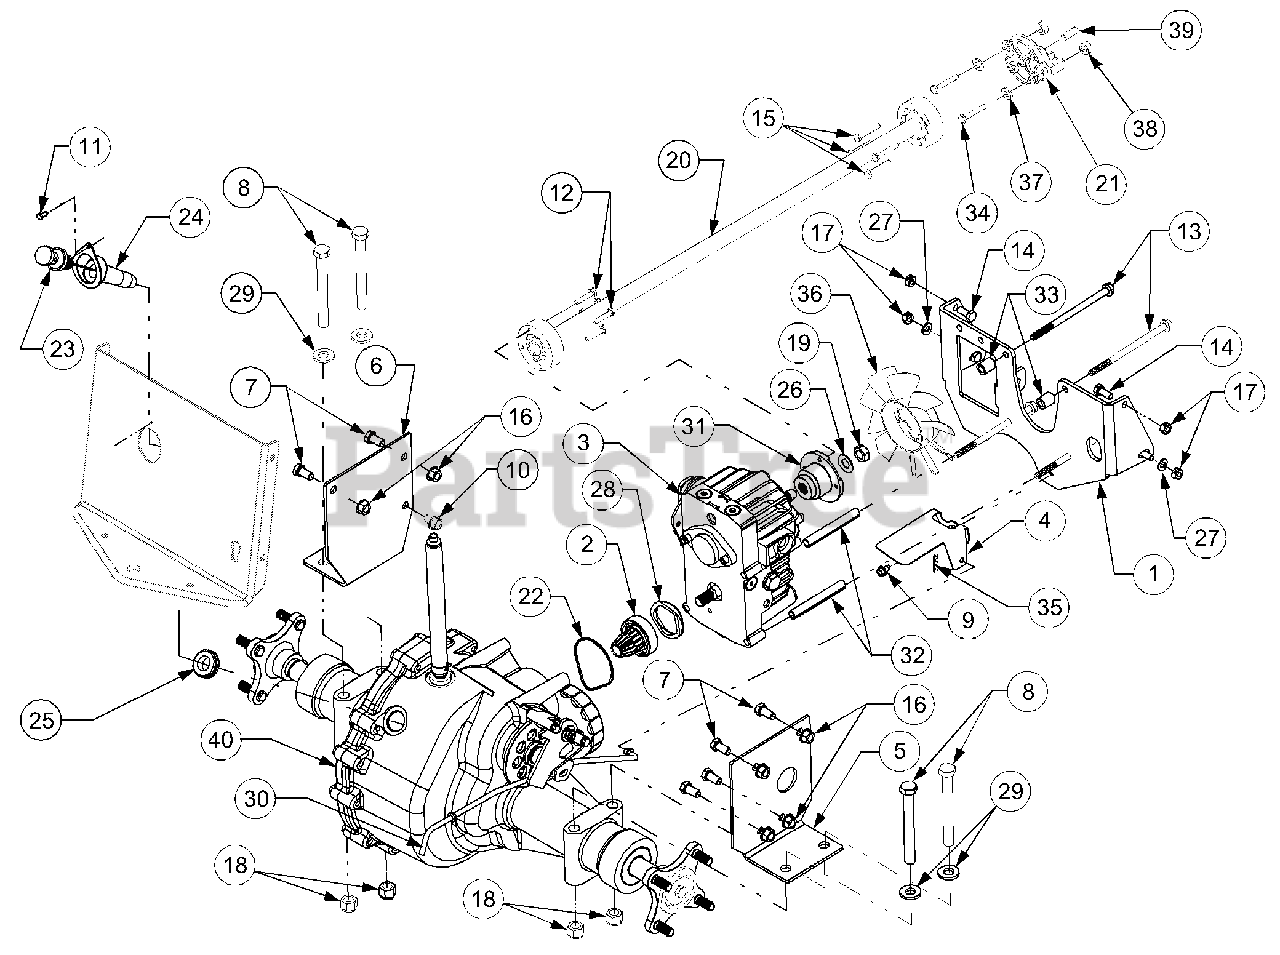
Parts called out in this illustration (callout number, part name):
1	Bracket, Torque
2	Gear Assembly, Pinion
3	Transmission, Hydrostatic
8	Screw, Hex Cap, 1/2-20 x 4.5 GR5
9	Scrw, Hx Wsh Hd Tapp, 1/4-20 x .5
10	Scrw, Hx Wsh Hd Tapp, 3/8-16 x .5
11	Scrw, Hx Wsh Hd Tapp, 10-16 x .44
12	Screw, Hex Patch, 1/4-20 x 1.25 GR5
13	Scrw, Hx Hd Tapp, 5/16-18 x 5.25
14	Screw, Hex Cap, 5/16-18 x .75 GR5
15	Screw, Hex Patch, 1/4-20 x 1.62 GR5
16	Nut, Hex Flange Lock, 3/8-16
17	Nut, Hex Cntr Lock, 3/8-16
18	Nut, Hex Nylon Lock, 1/2-20 GR2
19	Nut, Hex Top Lock Jam, 1/2-20
20	Shaft, Drive, 31.75 Lg
21	Adapter, Engine
22	Seal, Gland
23	Dipstick, Transmission
24	Holder, Dipstick
25	Grommet, Rubber, .75 x 1.063
26	Washer, Belleville
27	Washer, Flat, .344 x .688 x .065
28	Washer, Spring
29	Washer, Flat, .531 x 1.062 x .134
30	Rod, Hydro Dump Valve
31	Adapter, Hydro Pump
32	Spacer, Hydro, .323 x .443 3.51
33	Spacer, Hydro, .323 x .600 x .74
34	Screw, Hex Cap, 5/16-18 x 1.75 GR5
35	Internal Cotter Pin
36	Fan, Pump
37	Washer, Flat, .344 x .75 x .12
38	Spacer, .38 x .625 x .275
39	Pin, Locating, .352 Dia x 1.156
40	Transmission Assembly, Hydro - See "Hydro Transmission" for Parts Info.
